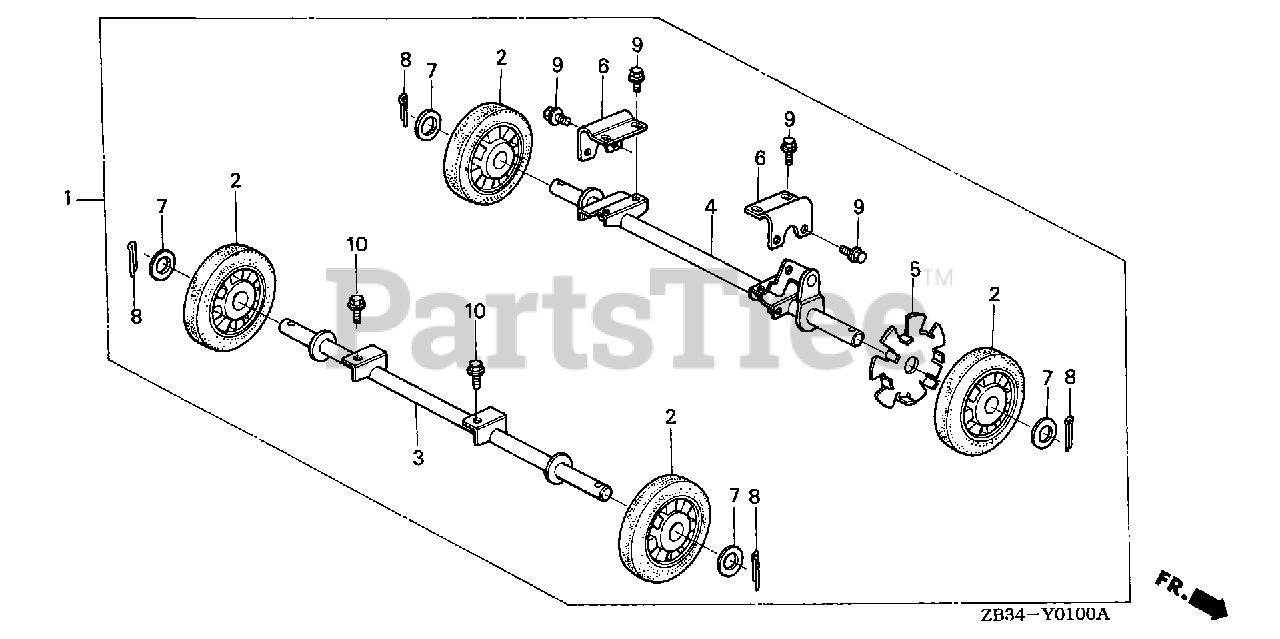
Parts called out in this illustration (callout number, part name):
1	WHEEL KIT
2	WHEEL
3	SHAFT, R. WHEEL
4	SHAFT, L. WHEEL
5	PLATE, LOCK
6	PLATE, PIPE SETTING
7	WASHER, PLAIN (20MM)
8	PIN, SPLIT (4.0X28)
8	PIN, SPLIT (4.0X30)
9	BOLT, FLANGE (6X14)
10	BOLT, FLANGE (8X16)
